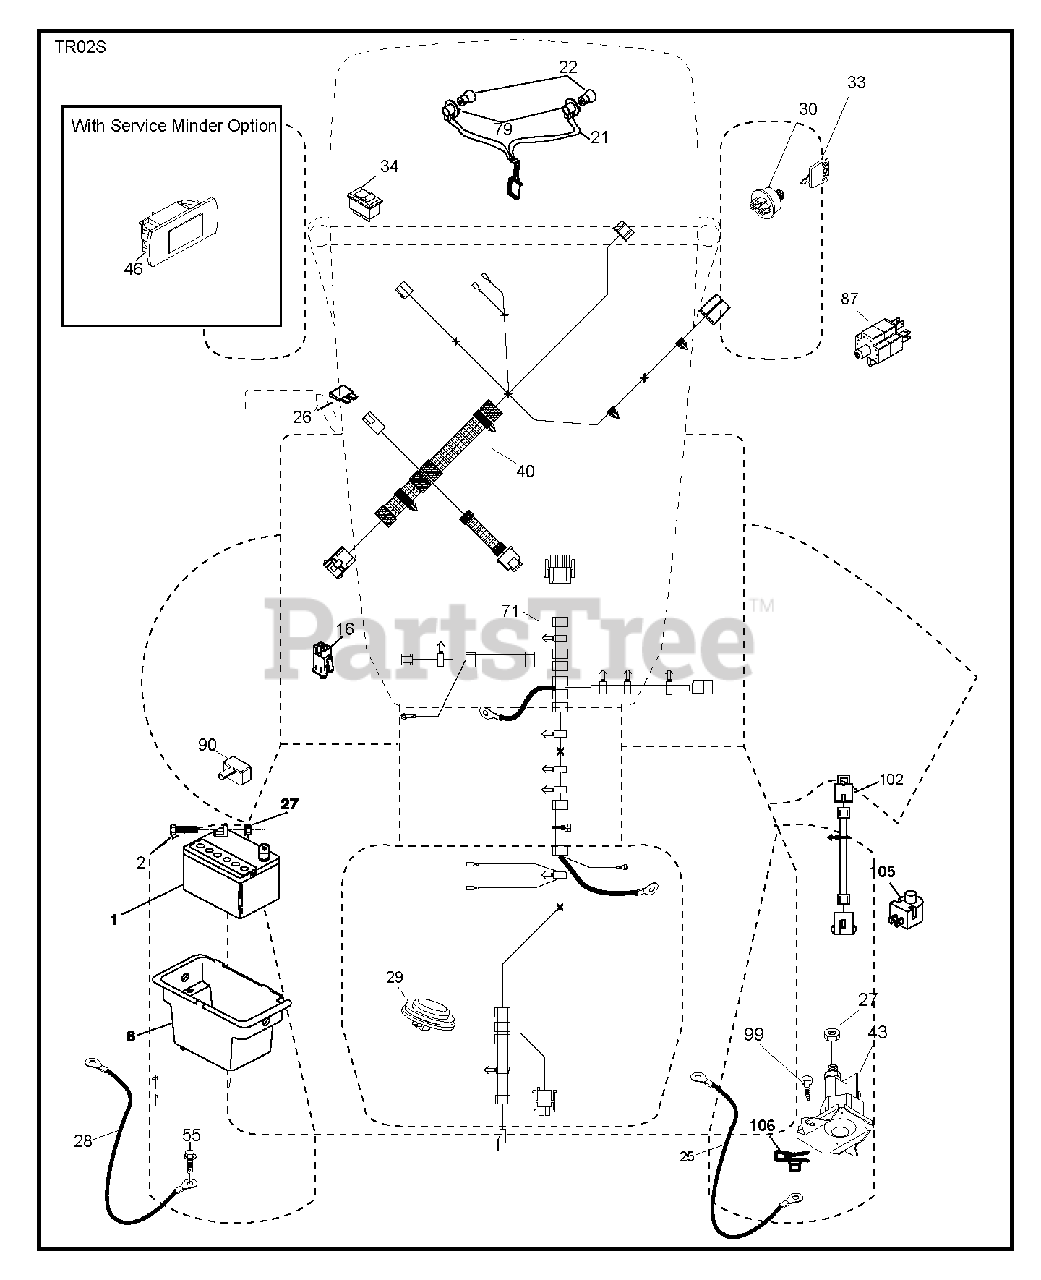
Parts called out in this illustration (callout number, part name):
1	Battery, Dry 30 Amp
2	BOLT.HEX.1/4.X.3/4.DICHROMATE
8	BOX.BATTERY.MNT.REAR.L
16	SWITCH INTERLOOK PUSH-IN
21	HARNESS.LIGHT W/4152J BULBS
25	CABLE.BATT.RED.8GA.17
26	FUSE 20AMP
27	NUT
28	CABLE.GROUND.REAR.BATTERY.8G
29	SWITCH.SEAT.DELTA.OPC.
30	SWITCH.IGN.DELTA.W.LGH.ROS
33	KEY.CHAIN.BLISTER.PACK.GEN.USA
40	HARNESS.DASH.CC.RRBATT.RDYSTRT
43	SOLENOID.W/BRASS.PLUNGER
46	RP GUAGE.SRVCMNDR.HRMTR.
55	SCREW 5/16"
71	HARNESS.CHASSIS.RRBATT.RDYSTRT
79	BULB HOLDER ASM.
87	SWITCH.INTRLCK.CLUTCH.
90	COVER.TERMINAL.BATTERY
99	SCREW HEXWSHR 1/4-20X3/4
102	HARNESS.PIGTAIL.VARIATOR.SD
105	REVERSE SWITCH
106	1/4-20 U NUT
